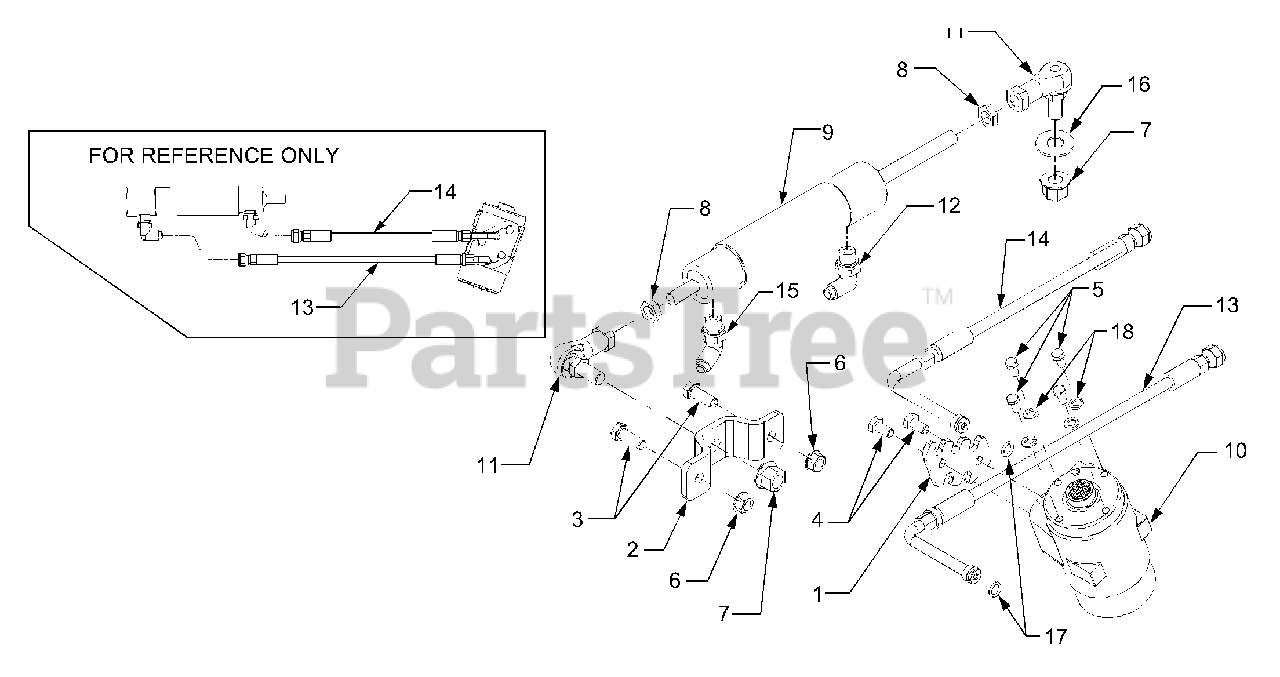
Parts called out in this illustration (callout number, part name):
1	Plate, Steering Pump Port
2	Bracket, Cylinder Mounting
3	Screw, Hex Cap 3/8-16 x 1.0 GR5
4	Screw, Hex Cap M8-1.25 x 16MM GR5
5	Screw, Hex Cap, M6 x 14MM
6	Nut, Hex Flange Lock, 3/8-16
7	Nut, Hex Flange Lock, M12 x 1.75
8	Nut, Hex, M12 x 1.75 RH
9	Cylinder, Steering
10	Pump, Hydraulic Steering
11	Ball Joint, 12MM x 1.75 RH
12	Fitting, 90 Degree Elbow
13	Hose, Front Steering
14	Hose, Rear Steering
15	Fitting, 45 Degree
16	Washer, Flat, .51 x 1.12 x .060
17	O-Ring, .426 x .566 x .070
18	Washer, Lock, 1/4"
